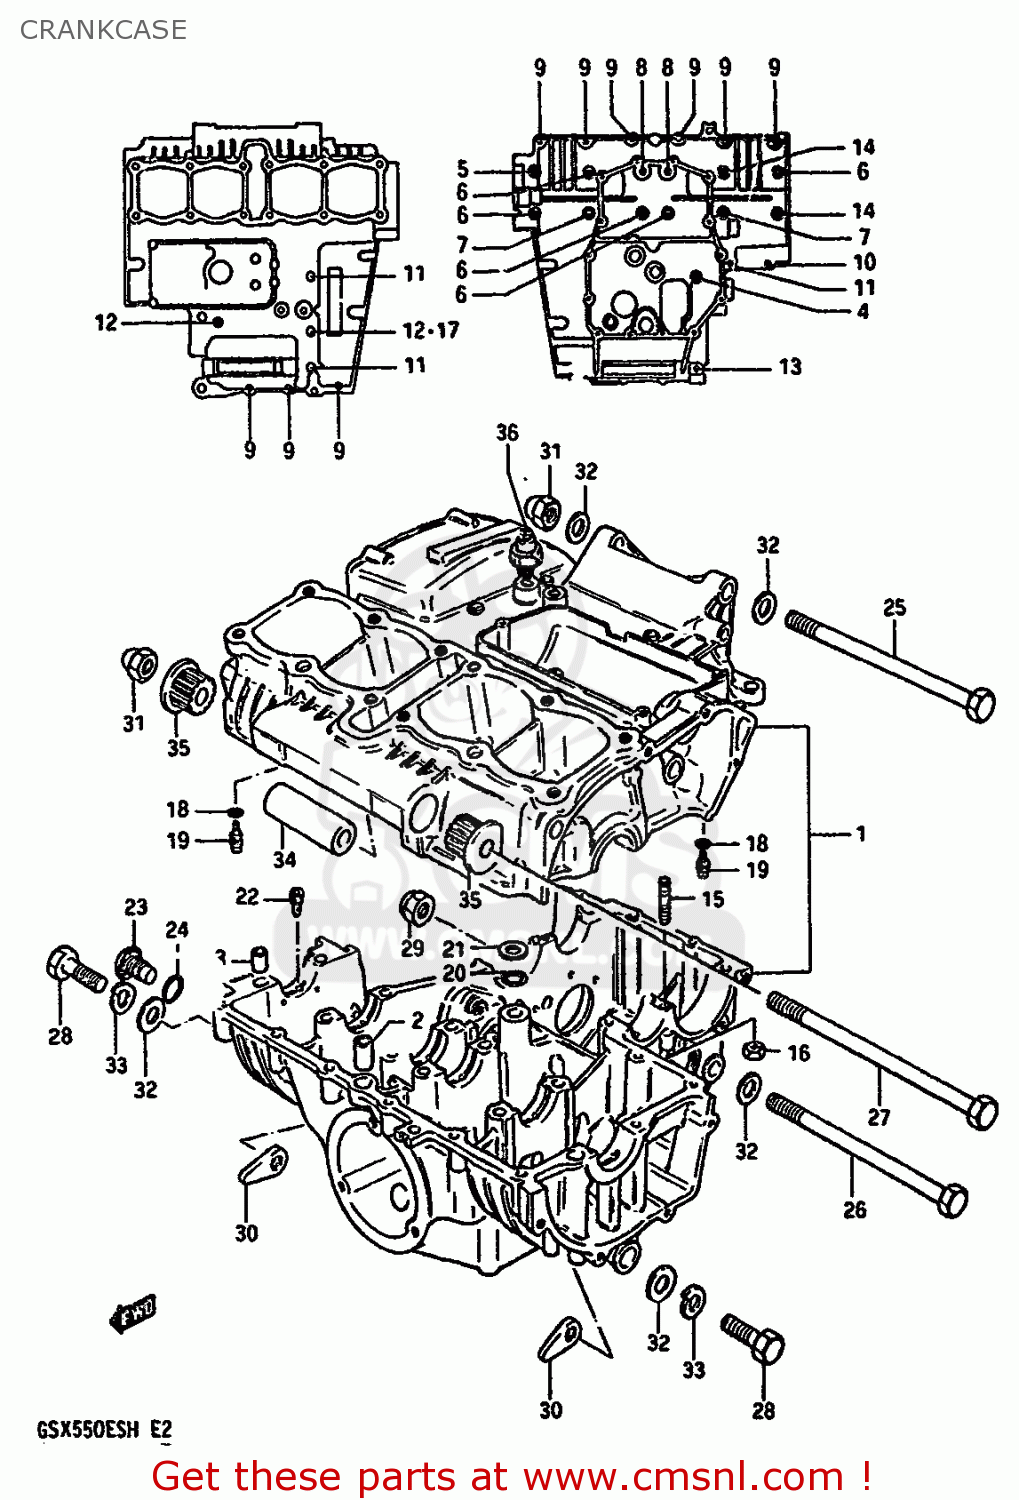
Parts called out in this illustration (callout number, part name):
1	CRANKCASE SET
2	PIN(10.4X13X22)
3	PIN (11X20)(SUS)
4	BOLT(6X100)
5	BOLT
6	BOLT
7	BOLT
8	BOLT
9	BOLT
10	BOLT 6X55
11	BOLT
12	BOLT (5X95)
13	BOLT 8X60
14	BOLT (8X90)
15	STUD BOLT
16	NUT 6MM
17	GASKET(6.2X13X1.2) (NAS)
18	O RING(D:1.2,ID:4)
19	JET,OIL GALLERY
20	O RING(D:3.2,ID:12.9)
21	WASHER,THRUST
22	JET,AIR
23	PLUG
24	O RING(D:2.4,ID:16.8)
25	BOLT
26	BOLT
27	BOLT
28	BOLT
29	NUT 10MM
30	NUT
31	NUT
32	WASHER
33	WASHER,LOCK
34	SPACER (10.2X16X105.5)
35	BUSH
36	SWITCH ASSEMBLY
